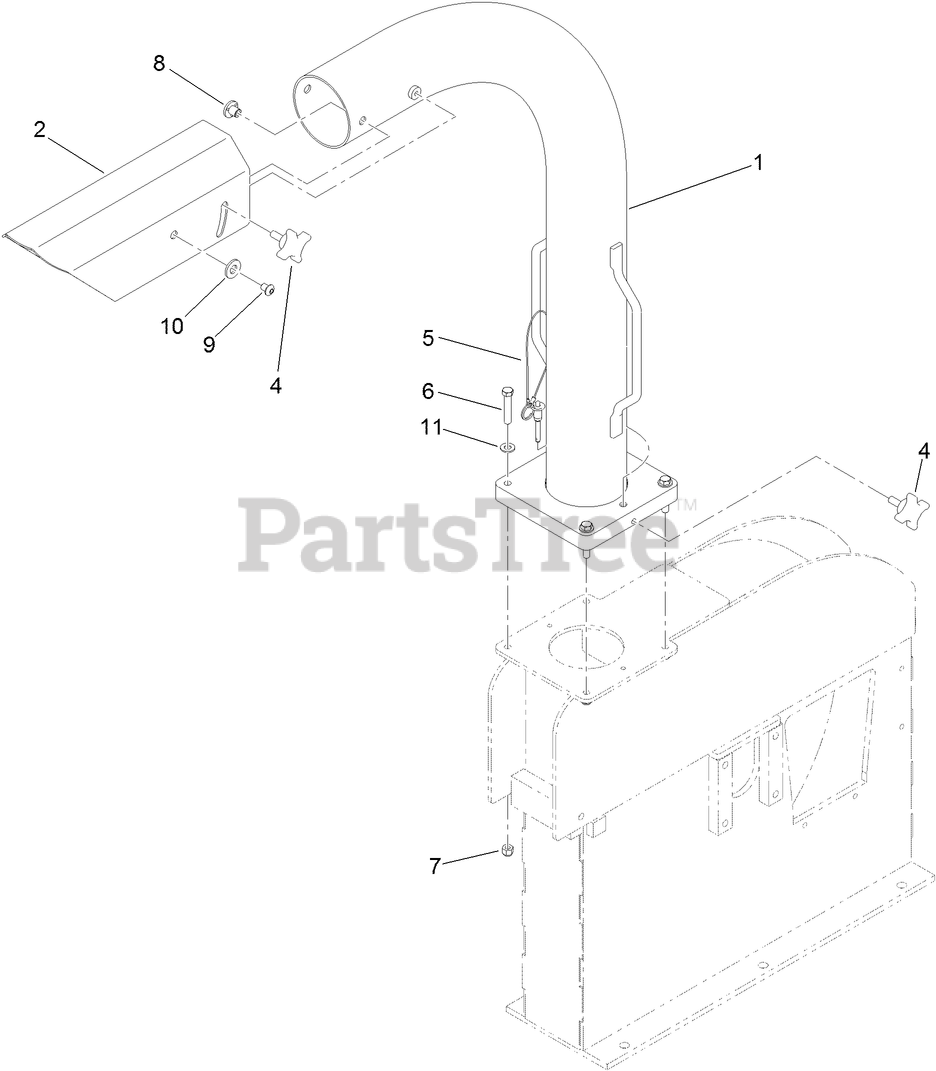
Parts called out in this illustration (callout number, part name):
1	EXIT CHUTE ASM
2	DEFLECTOR-CHUTE
5	PIN-LOCKING
6	SCREW-HH
7	NUT-LOCK, NI
8	NUT-WELD
9	SCREW-HSBH
10	WASHER-THRUST, PLAIN
11	WASHER-FLAT
